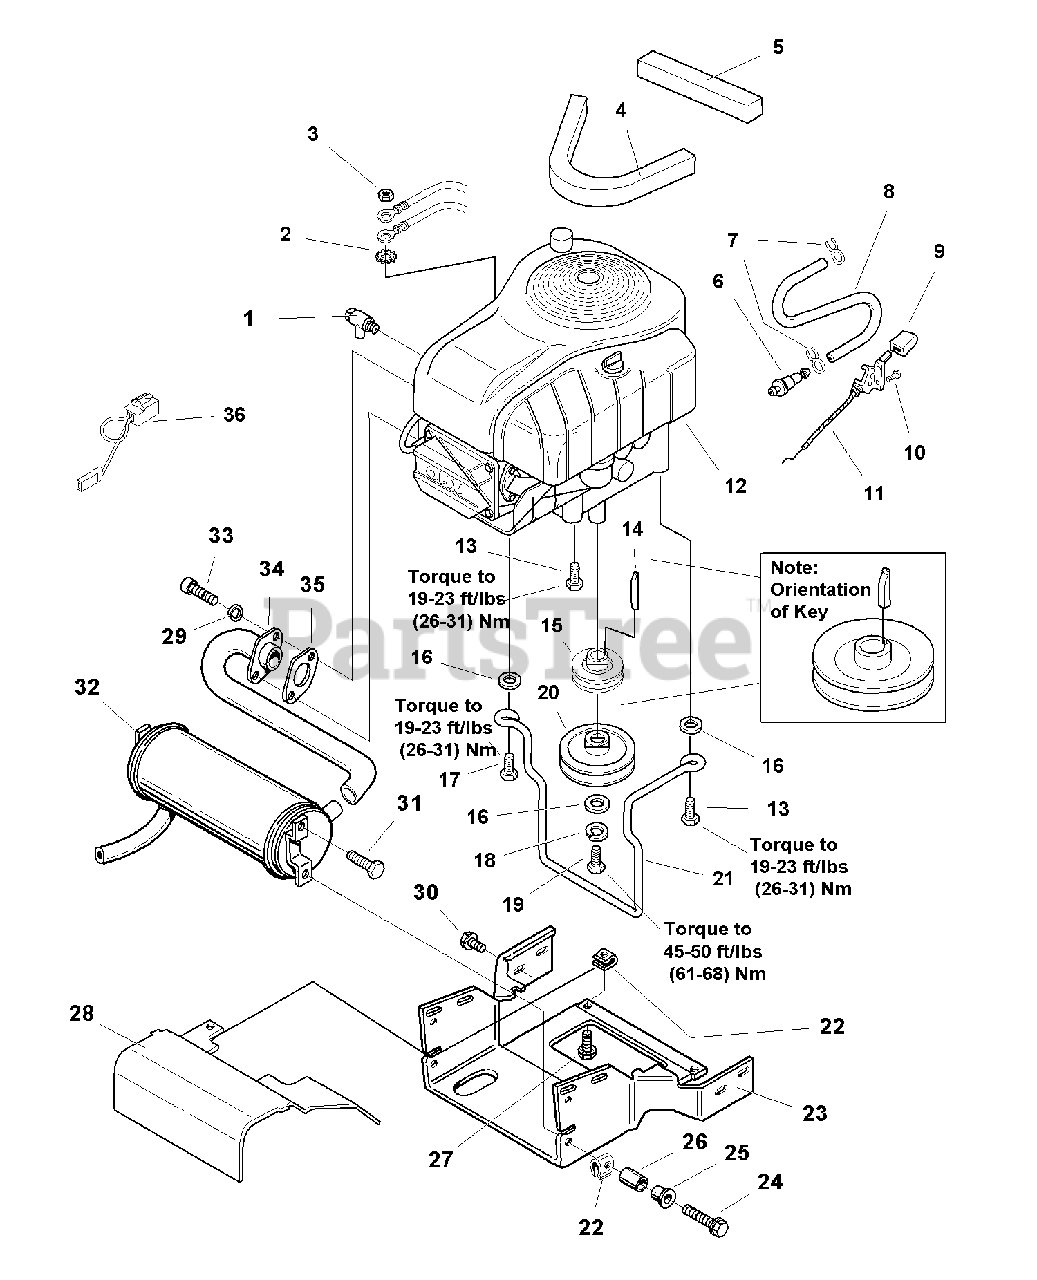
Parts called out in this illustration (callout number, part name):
1	VALVE-SHUT OFF
2	LOCKWASHER, External Tooth 3/8
3	NUT, Hex 3/8-16
4	SEAL, Foam
6	FILTER, Fuel
7	CLAMP, Hose Type E
8	HOSE, 12" Long
10	CAPSCREW, Hex Washer Head 1/4-14 x 5/8
11	CABLE, Throttle Control, 14" Long
12	ENGINE-15/16/17HP Briggs & Stratton INTEK SINGLE
13	CAPSCREW, Hex Washer Head, Taptite, 3/8-16 x 1-1/2
14	KEY, Hi-Pro
16	WASHER
17	CAPSCREW, Hex Washer Head, Taptite, 3/8-16 x 2
18	LOCKWASHER, 7/16
19	CAPSCREW, 7/16-20 x 2
20	PULLEY, 5.40 O.D.
22	NUT, Speed 5/16-18
23	DUCT, Muffler
24	CAPSCREW, Hex Flange Lock, 5/16-18 x 1-1/4
27	CAPSCREW, Hex Flange Lock, 5/16-18 x 3/4
28	DUCT, Muffler, Upper
29	LOCKWASHER, 5/16
30	CAPSCREW, Hex Washer Head, Taptite, 5/16-18 x 1/2
31	CAPSCREW, Hex Washer Head, Taptite, 1/4-20 x 3/8
33	CAPSCREW, 5/16-18 x 3/4, G8
34	PIPE, Exhaust
36	WIRE ASSEMBLY, Briggs & Stratton
